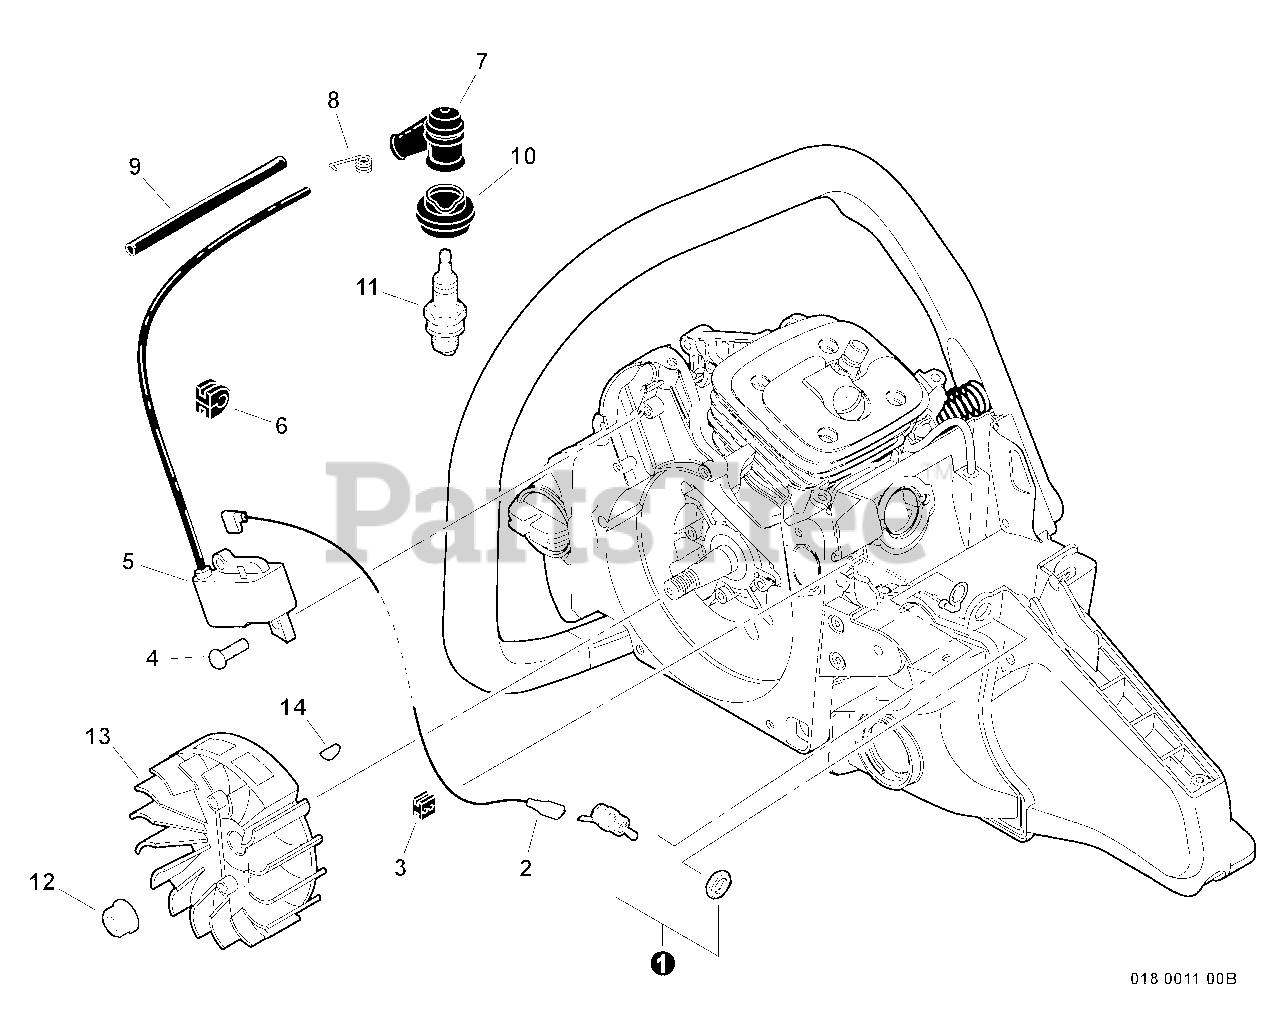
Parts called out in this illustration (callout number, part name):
1	SWITCH, ON-OFF
2	LEAD - IGNITION L= 280
3	GROMMET, LEAD
4	BOLT, TORX 5×16
5	COIL, IGNITION
7	CAP, SPARK PLUG
8	TERMINAL, SPARK PLUG
9	TUBE, IGNITION COIL 6×7.2×70
10	SEAL, SPARK PLUG
11	SPARK PLUG - BPM8Y
11	SPARK PLUG - BPMR8Y
12	NUT, FLANGE M8
13	FLYWHEEL
14	KEY, WOODRUFF
